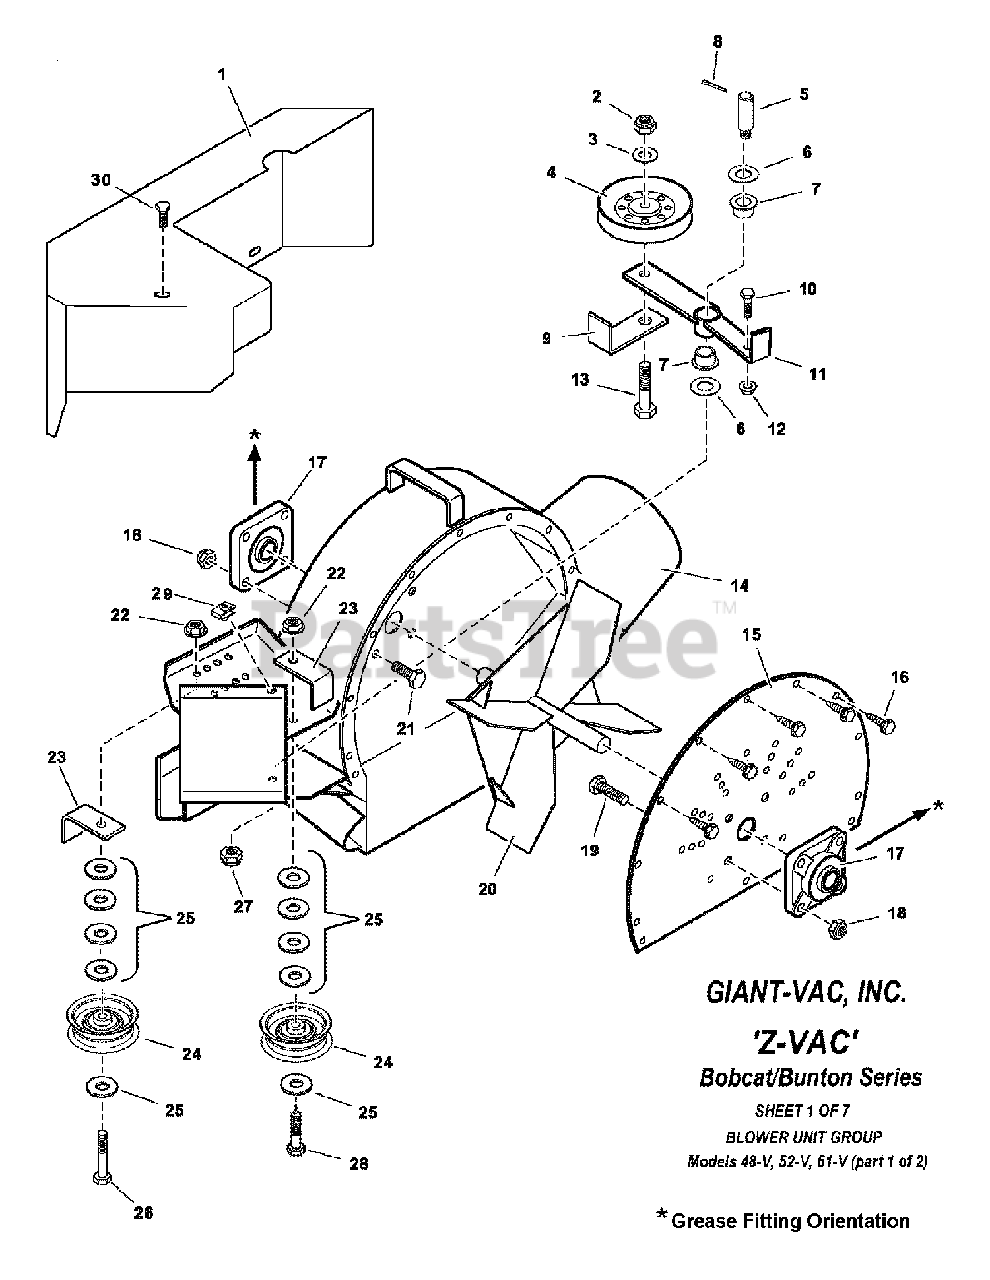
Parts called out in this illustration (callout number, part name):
1	WELDMENT, Blower Belt Guard
2	NUT, 1/2-13 Hex Nyloc
3	WASHER, 1/2" Flat SAE
4	PULLEY, A Groove Idler, Steel
5	IDLER STUD (3/8-24 thread)
6	WASHER, 9/16 Flat, Narrow Type
7	FLANGE BEARING, 9/16" I.D.
8	COTTER PIN, 1/8 x 3/4"
9	BELT RETAINER, Idler
10	SCREW, 5/16-18 x 1-1/4" Hex Head Cap, GR5
11	WELDMENT, Idler Arm
12	NUT, 5/16-18 Hex Flange Lock
13	SCREW, 1/2-13 x 2-1/2" Hex Head Cap, GR5
14	WELDMENT, Blower Housing
15	BACK PLATE, Blower
16	SCREW, 5/16-18 x 3/4" Hex Washer Self-Tap
17	BEARING, Pillow Block, Blower
18	NUT, 7/16-14 Hex Center Lock
19	SCREW, 7/16-14 x 1-1/2" Hex Head Cap, GR5
20	WELDMENT, Impeller, Fast Vac Blower
21	SCREW, 7/16-14 x 1-1/4" Hex Head Cap, GR5
22	NUT, 3/8-16 Hex Flange Lock
23	BELT RETAINER
24	PULLEY, Flat Idler, 2-3/4" O.D.
25	WASHER, 3/8" SAE Flat
26	SCREW, 3/8-16 x 2-1/4" Hex Head Cap, GR5
27	NUT, 3/8-24 Hex Nyloc
28	SCREW, 3/8-16 x 2", Hex Head Cap, GR5
29	U-CLIP, 5/16-18
30	SCREW, 5/16-18 x 3/4" Hex Washer Self-Tap
